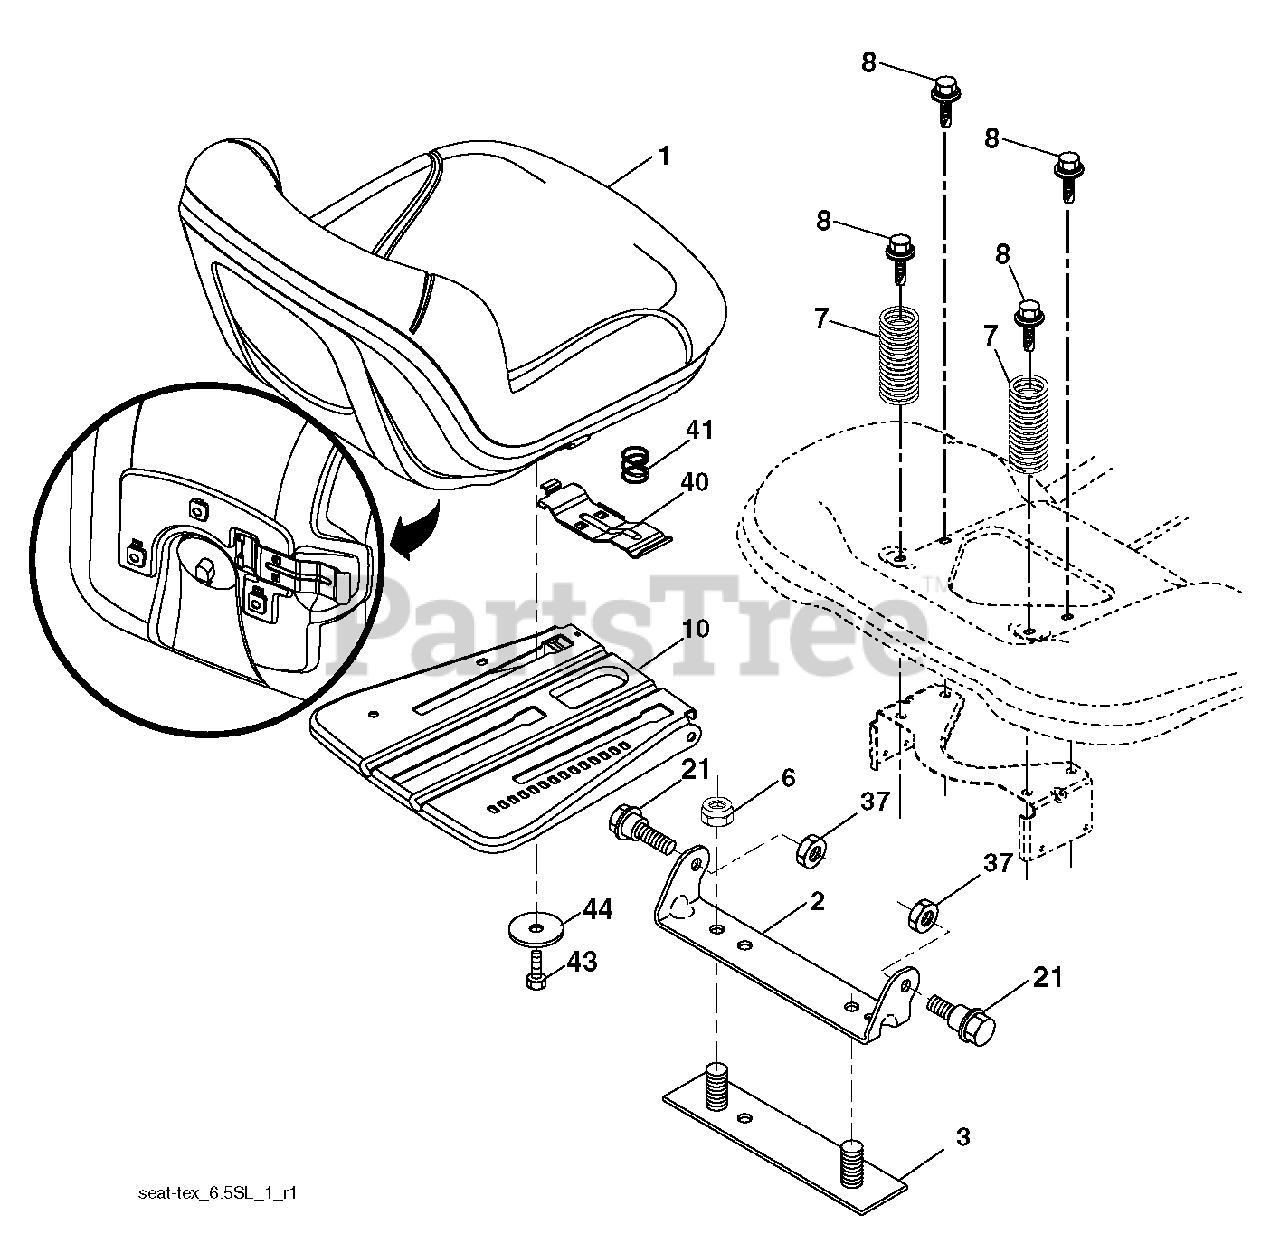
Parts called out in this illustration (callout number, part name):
1	SEAT.TH150.MS498.GRY.HUSQ.TEX
2	BRKT.PIVOT.FENDER
3	STRAP
6	NUT
7	SPRING COMPRESSION
8	BOLT, 5/16-18 X 1 3/4
10	PAN.ASM.SEAT.3PT
21	BOLT.SHOULDER.5/16-18
37	NUT.71038.31-18.HEX.NYLOCK
40	HANDLE.SLIDE.SEAT.TEX.BLACK
41	SPRING.LATCH.SEAT.TEX
44	WASHER 13/32 X 2-3/8 X 12GA
